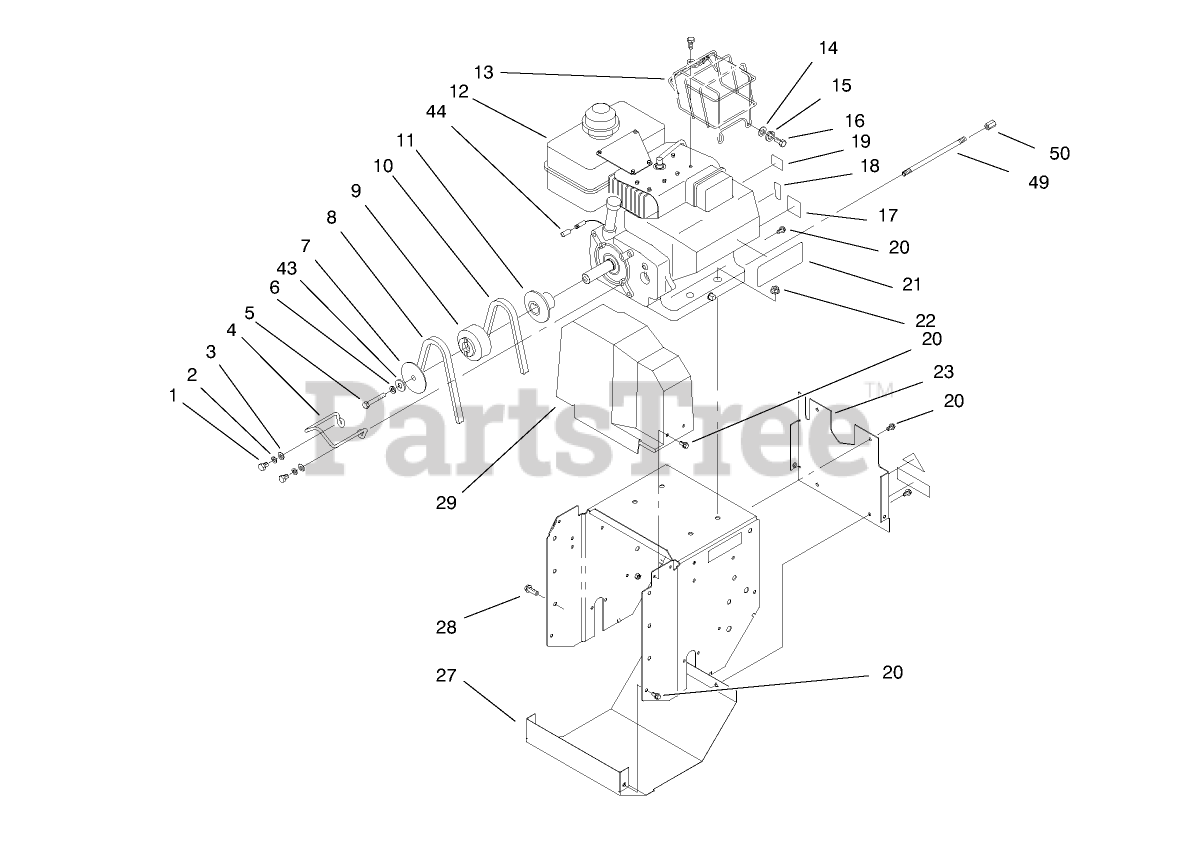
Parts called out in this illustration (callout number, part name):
1	SCREW-HH
2	WASHER-LOCK
3	WASHER-PLAIN
4	GUIDE - BELT
5	SCREW-HH
6	WASHER-LOCK
7	SHEAVE-HALF, IMPELLER
8	V-BELT, IMPELLER
9	PULLEY - ENGINE CENTER
10	V BELT-TRACTION
13	GUARD - MUFFLER
14	TECH# 650147
15	TECH# 650979
16	SCREW
17	DECAL - PRIMER
18	DECAL-THROTTLE
19	DECAL-CHOKE
20	SCREW-HWH
21	DECAL-WARNING, HOT SURFACE
21	DECAL-SURFACE, HOT
22	NUT-HF
28	SCREW-HWHTF
29	COVER - UPPER BELT
43	WASHER
44	CAP-WIRE, LITE
49	NIPPLE-PIPE
50	CAP-PIPE
